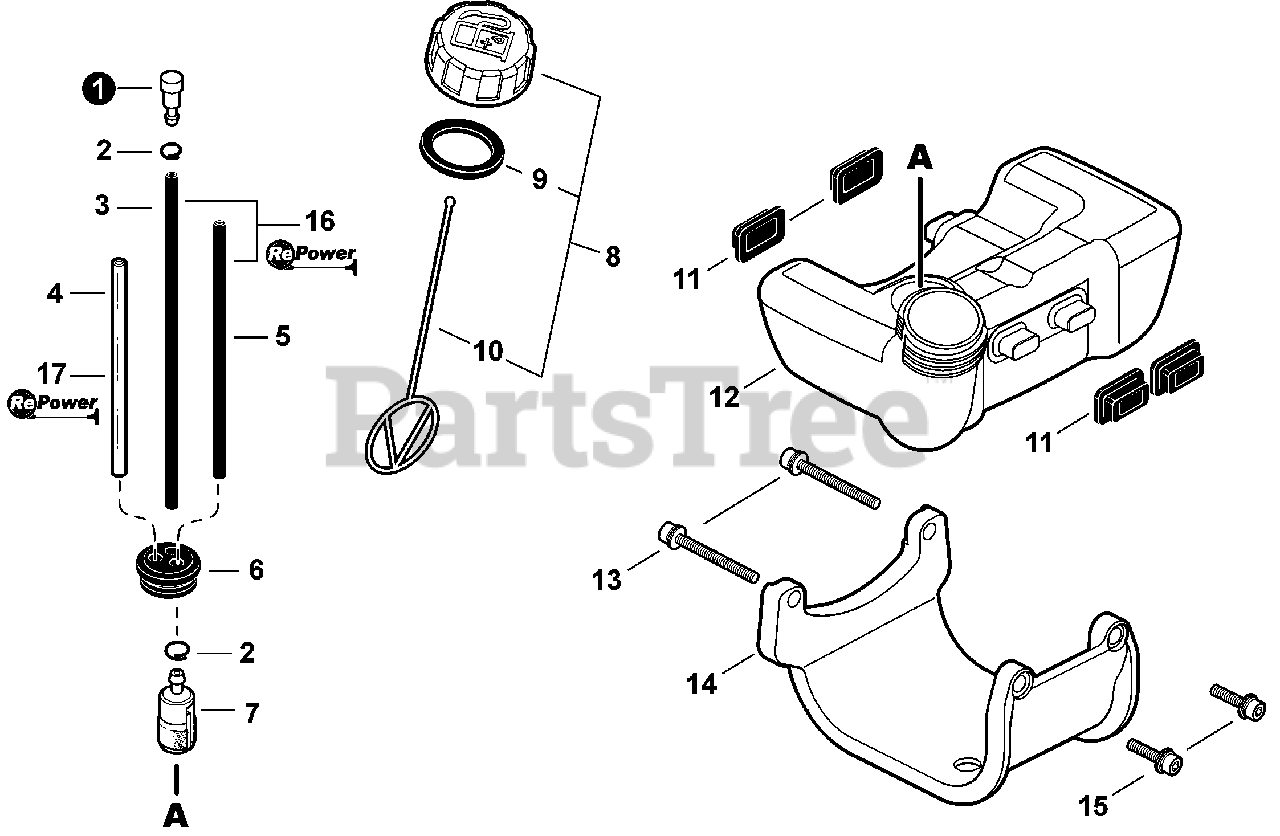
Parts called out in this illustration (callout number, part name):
1	VENT ASSY
2	CLIP Ø6.5 MM
3	PIPE, FUEL 3×6×105 BLACK
4	PIPE, FUEL 3×6×85 CLEAR
5	PIPE, FUEL 3×6×210 BLACK
6	GROMMET, FUEL
7	FILTER, FUEL 125-528
8	CAP ASSY, FUEL
9	GASKET, FUEL CAP
10	CONNECTOR, CAP L= 123
11	CUSHION, FUEL TANK
12	TANK, FUEL
13	BOLT 5×40
14	GUARD, FUEL TANK
15	BOLT 5×18
16	BULK PIPE - 3×6 MM BLACK (4 PIECES×2 M)
17	BULK PIPE - 3×6 MM CLEAR (4 PIECES×2 M)
